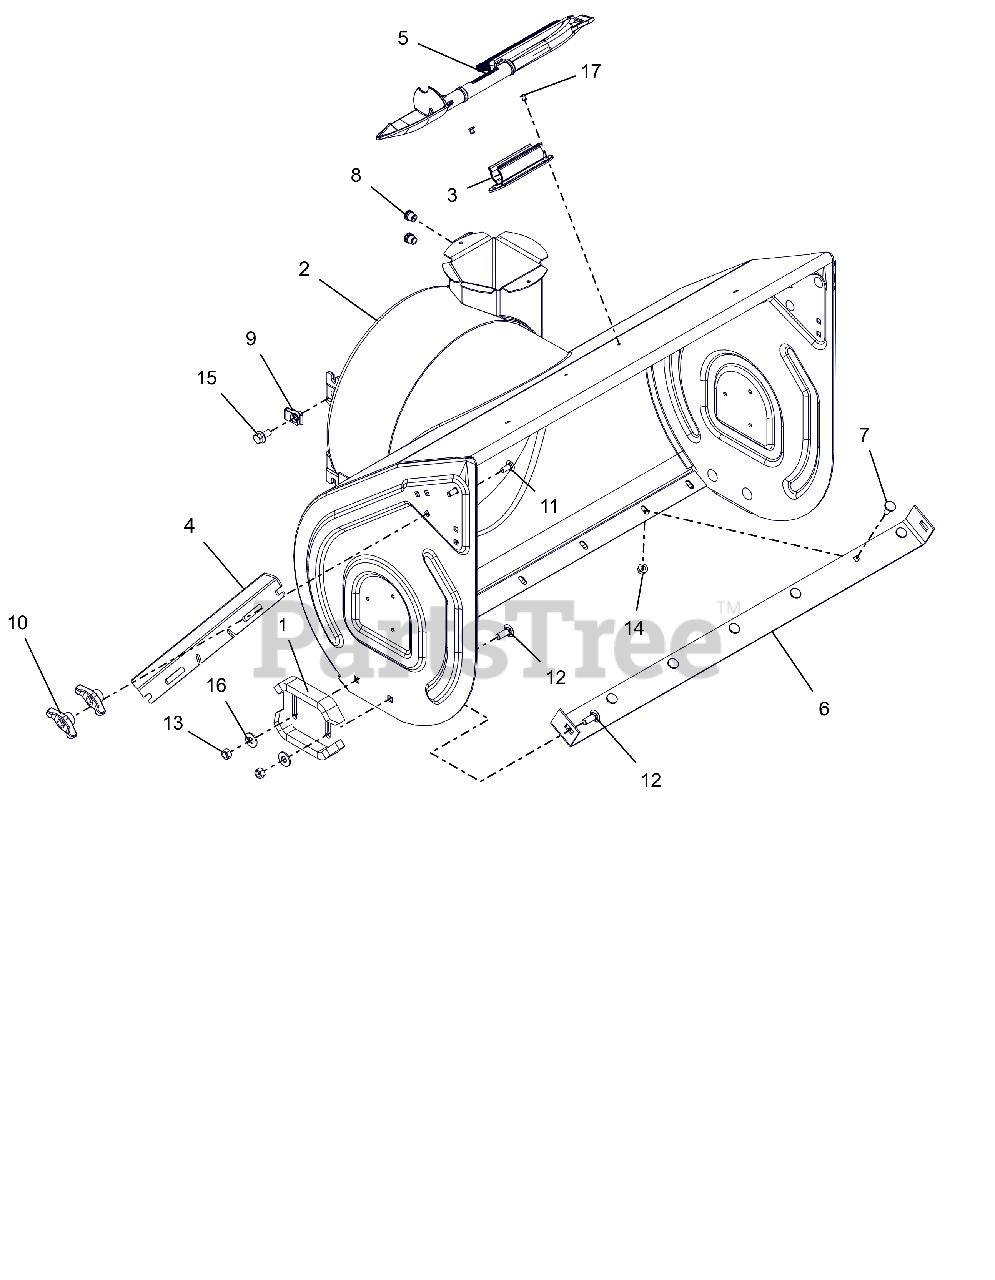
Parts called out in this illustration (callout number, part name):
1	RUNNER, SKID SHOE
2	BLOWER HOUSING W/DECAL 32"
3	MOUNT, SNOW CLEAN OUT
4	CUTTER, DRIFT
5	DEVICE, SNOW CLEAN OUT W/BRUSH
6	BLADE, SCRAPER-32"
7	BOLT, MODIFIED HEAD CARRIAGE
8	NUT,THD,INSERT .38-16 ZC120
9	NUT-RTNR .375-16X.37
10	KNOB,WING .31-18 UNC NYL/TALC
11	BLT, RHSSN.31-18X.750 G5 ZCC
12	BLT,RHSSN .38-16X1.00 G5 ZCC
13	NUT-LK-CTR .38-16 ZC120
14	NUT-LK-TOP-FLG .312-18 GF ZCC
16	WSHR,FLT .438X1.00X.083 ZCC
17	RVT, POP .1875 ZCC
